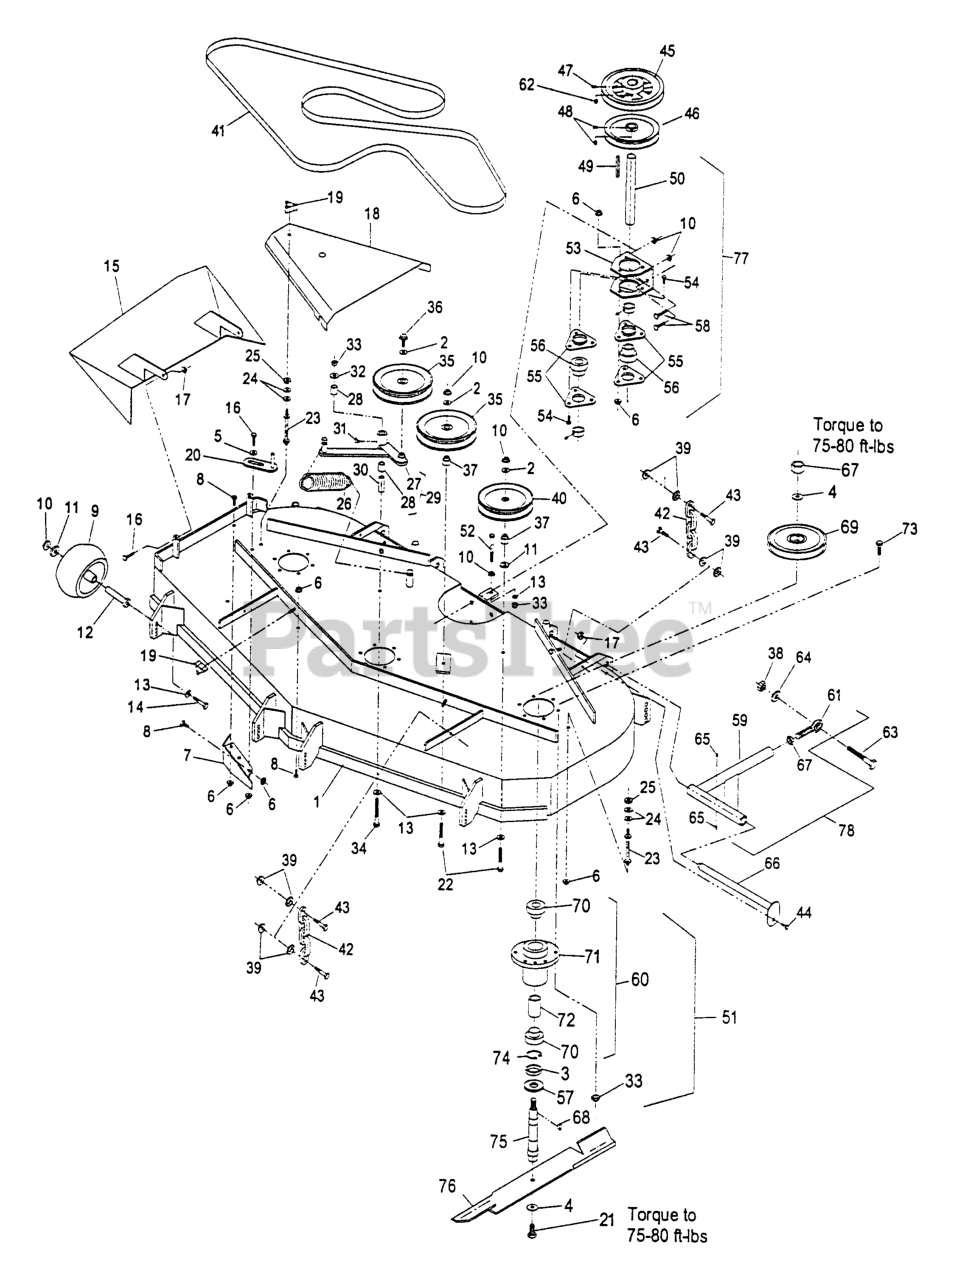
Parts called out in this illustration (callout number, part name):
3	SPACER-PULLEY/BEARING
4	WASHER-SPRING
5	WASHER-SPRING
7	WLD,BAFFLE DISCHARGE
9	ROLLER-SCALP, ANTI
12	BUSHING-ROLLER
15	WLD,CHUTE DISCHARGE
18	SHIELD,BELT 52
19	KNOB-3 PRONG
20	GUIDE-BELT
23	STUD-SHIELD, BELT (SHORT)
28	SLEEVE-BEARING
30	BUSHING
37	BUSHING-IDLER
40	PULLEY-IDLER
41	BELT,BLADE DRIVE 52
42	CHAIN-LIFT, DECK
43	SCREW-CAP, HH
46	SHEAVE,SPLIT STEEL
48	SCREW-SET
49	KEY,MACH 1/4X1/4X2-5/8
50	JACKSHAFT,DECK DRIVE
51	CUTTER HOUSING ASSY
53	BRACKET,JACKSHAFT
55	HOUSING-FLANGE
56	BEARING,W/COLLAR
57	GUARD-BEARING, BOTTOM
61	BALLJOINT-SPHERICAL
62	SCREW-SET
66	PIN-STRUT
69	SHEAVE,BLADE DRIVE
70	BEARING
72	SPACER-BEARING
75	SHAFT,SPINDLE SHORT
77	DK DR. BRG. ASSY
